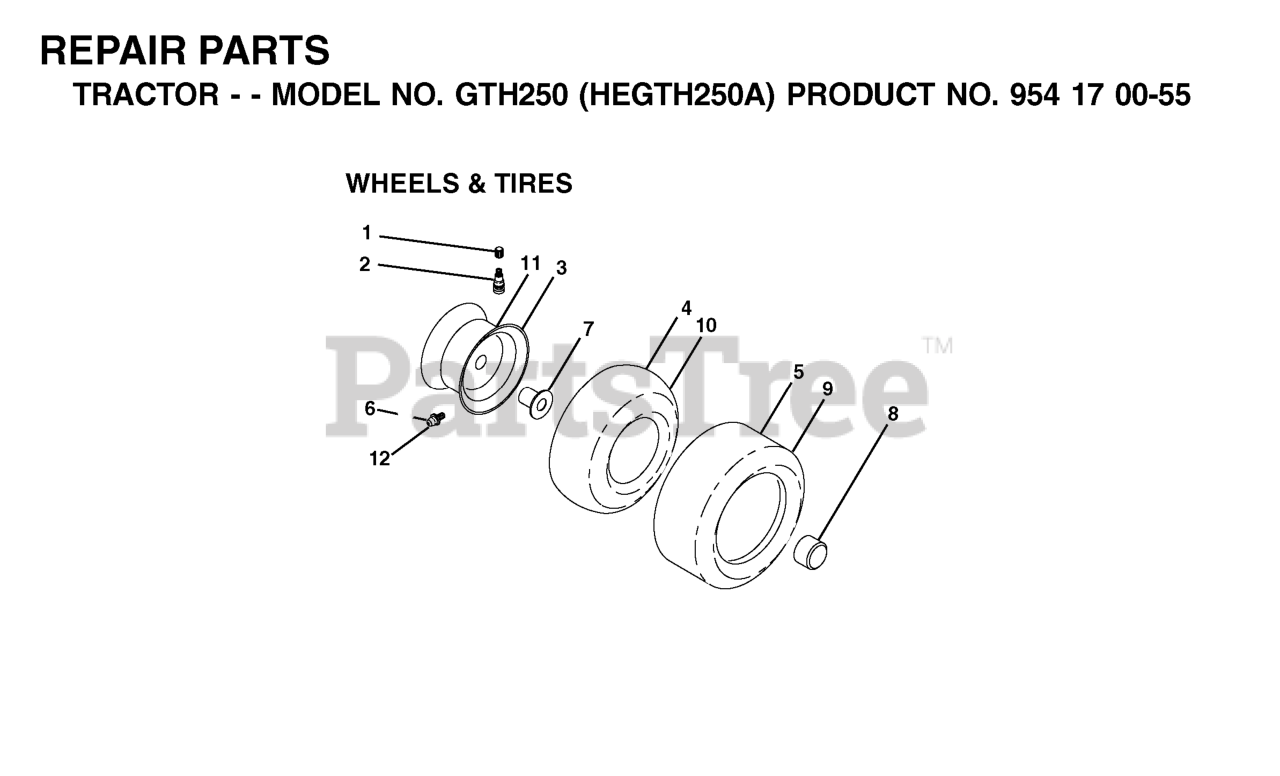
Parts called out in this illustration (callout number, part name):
2	VALVE STEM LT
3	RIM ASSEMBLY, FRONT
4	TUBE.16X6.5/7.5-8
5	TIRE HEAVY DUTY
6	FITTING LT
7	BEARING T
8	CAP, AXLE BLK
9	TIRE HEAVY DUTY
10	TUBE.23X9.5-12
11	RIM.ASM.12X7.REAR.SILVER
12	ZERK FITTING M
